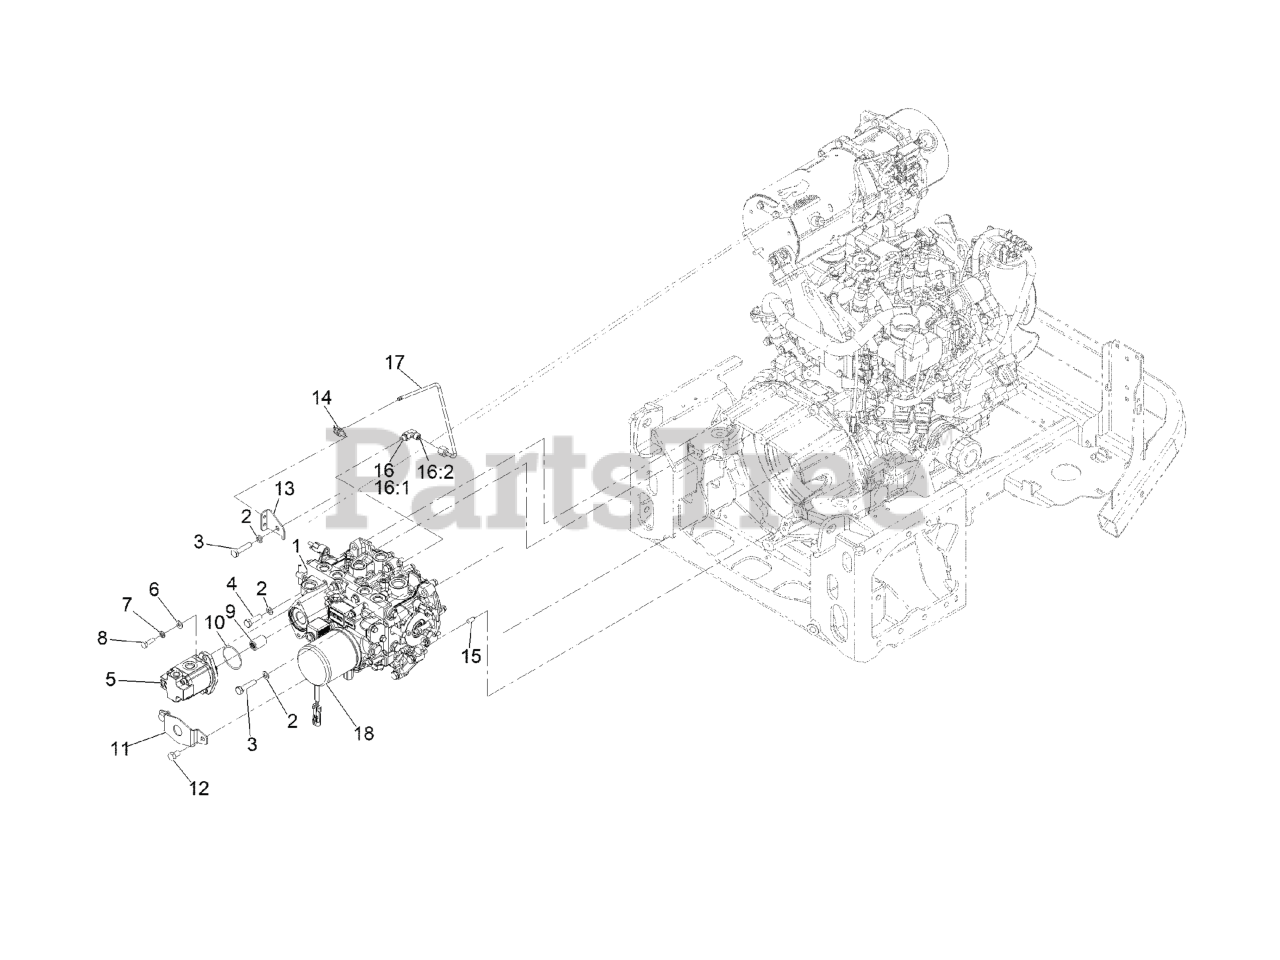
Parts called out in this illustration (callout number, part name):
1	TRANSMISSON ASM
2	WASHER-LOCK
3	SCREW-HH
4	SCREW-HH
5	HYD GEAR PUMP ASM
6	WASHER-PLAIN
7	WASHER-LOCK
8	SCREW-HH
9	COUPLER-SPLINE
11	SHIELD-SEAL
12	SCREW-HH
13	SUPPORT-TUBE
14	CLIP-TIE
15	PIN-DOWEL
16	FITTING-ELBOW, 90 DEG
16:1	O-RING
16:2	O-RING
17	TUBE ASM
18	FILTER-OIL, HYD
